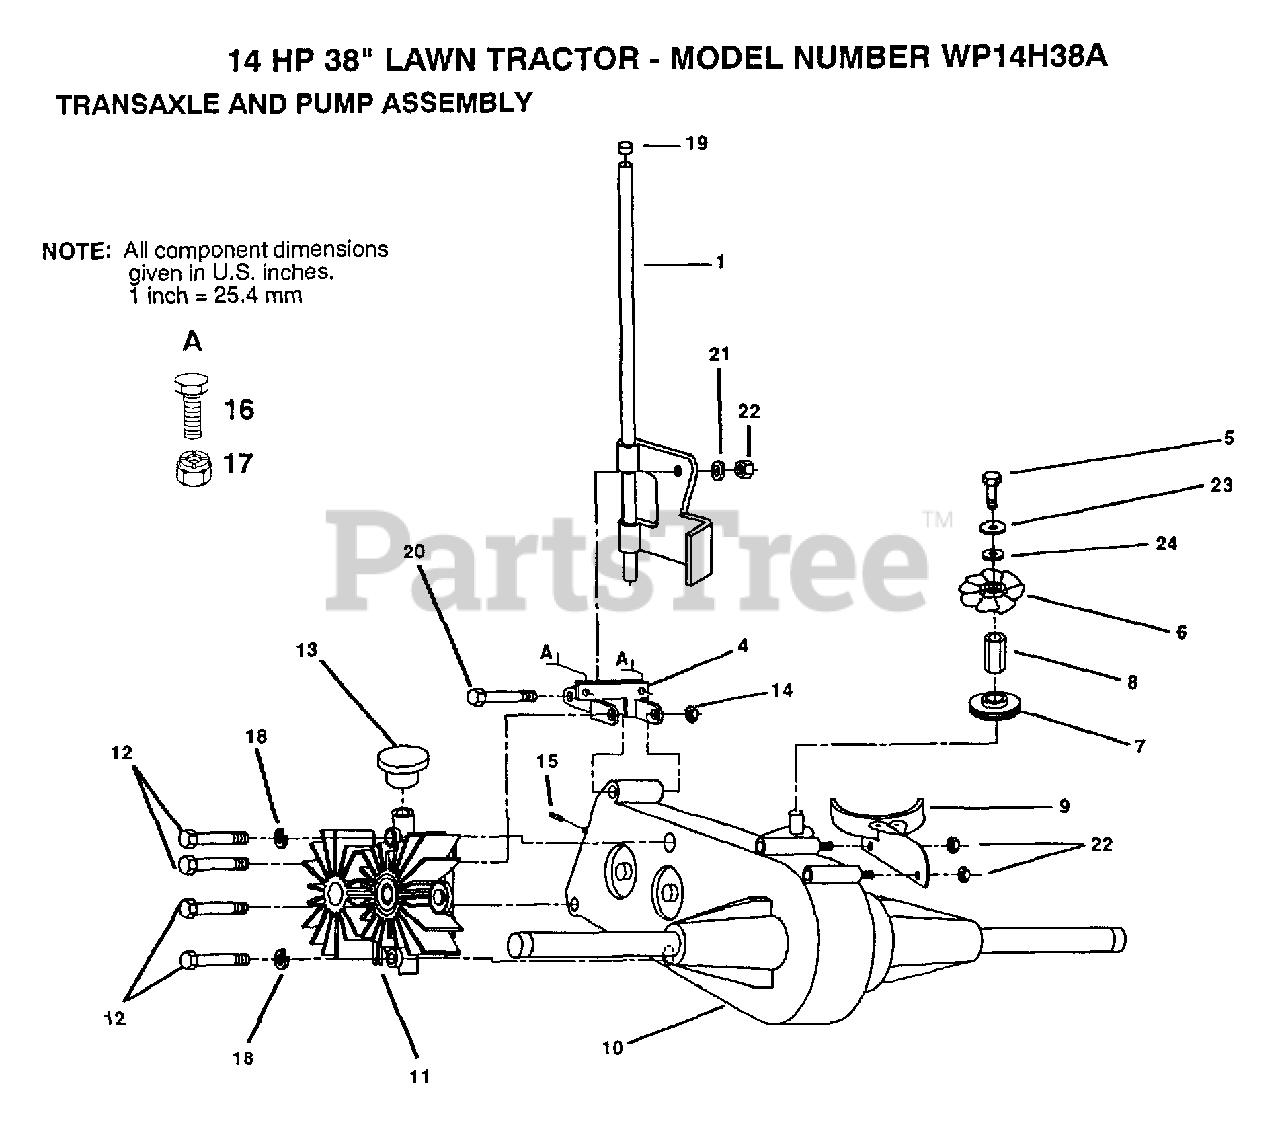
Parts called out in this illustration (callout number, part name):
1	CONTROL ASSY
4	BRACKET
6	FAN
7	PULLEY TRANSAXLE
8	STANDOFF
9	GUARD ASSY
10	TRANSAXLE.AGRIFAB
11	PUMP.BDU-10S-114
12	BOLT
13	PUMP.2003081.
15	SPRING
18	LOCKWASHER
19	PLUNGER CAP T
20	BOLT T
21	WASHER T
23	WASHER
24	LOCKWASHER
